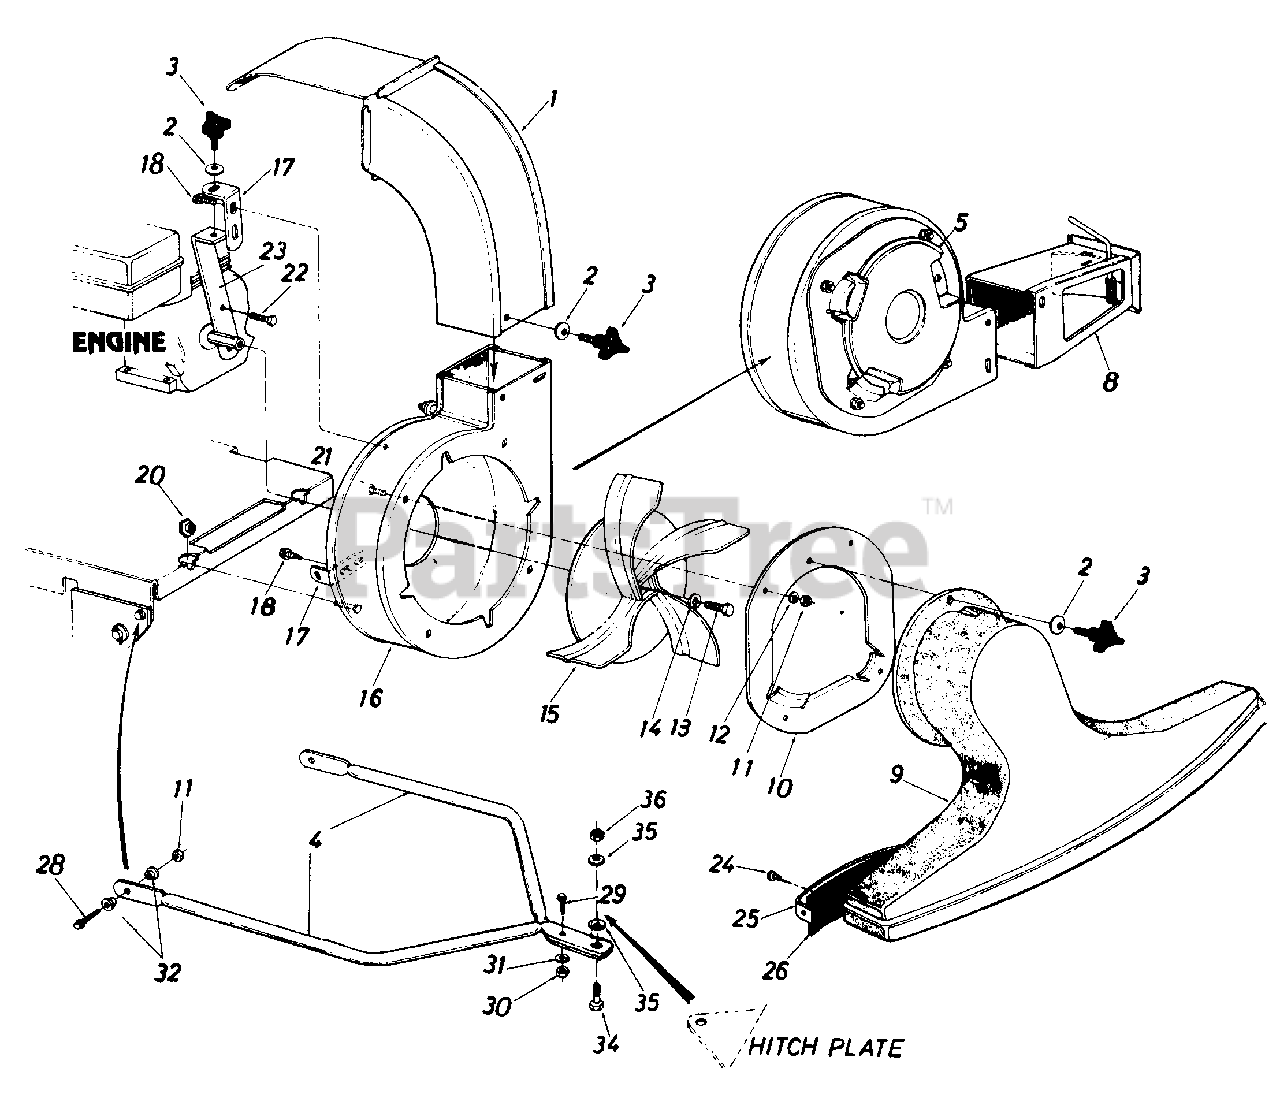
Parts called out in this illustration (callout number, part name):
3	3-Arm Thumb Scr. 5/16-18 x .75" Lg.
10	Nozzle Plate Ass'y.
11	Hex Nut 5/16-18 Thd.
12	L. Wash. 5/16" I.D.
13	Hex Bolt 3/8-24 x 1.25" Lg.
14	L.-Wash. 3/8" I.D. H.D.
15	Air Vane Plate Ass y.
20	Hex Shoulder Nu .50 I.D.
21	Carriage Bolt 5/16-18 x .62" Lg.
22	Hex Locking Bolt 5/16-24 x .75" Lg.
28	Hex Bolt 5/16-18 x 1.00" Lg.*
29	Truss Mach. Scr. 1/4-20 x .75" Lg.*
30	Hex Nut 1/4-20 Thd.*
31	L.-Wash. 1/4" I.D.*
32	Shoulder Spacer
34	Shld. Bolt .496 Dia.
35	Belleville Wash. .39 I.D. x 1.12 O.D.
36	Hex Jam L-Nut 3/8-16 Thd.
